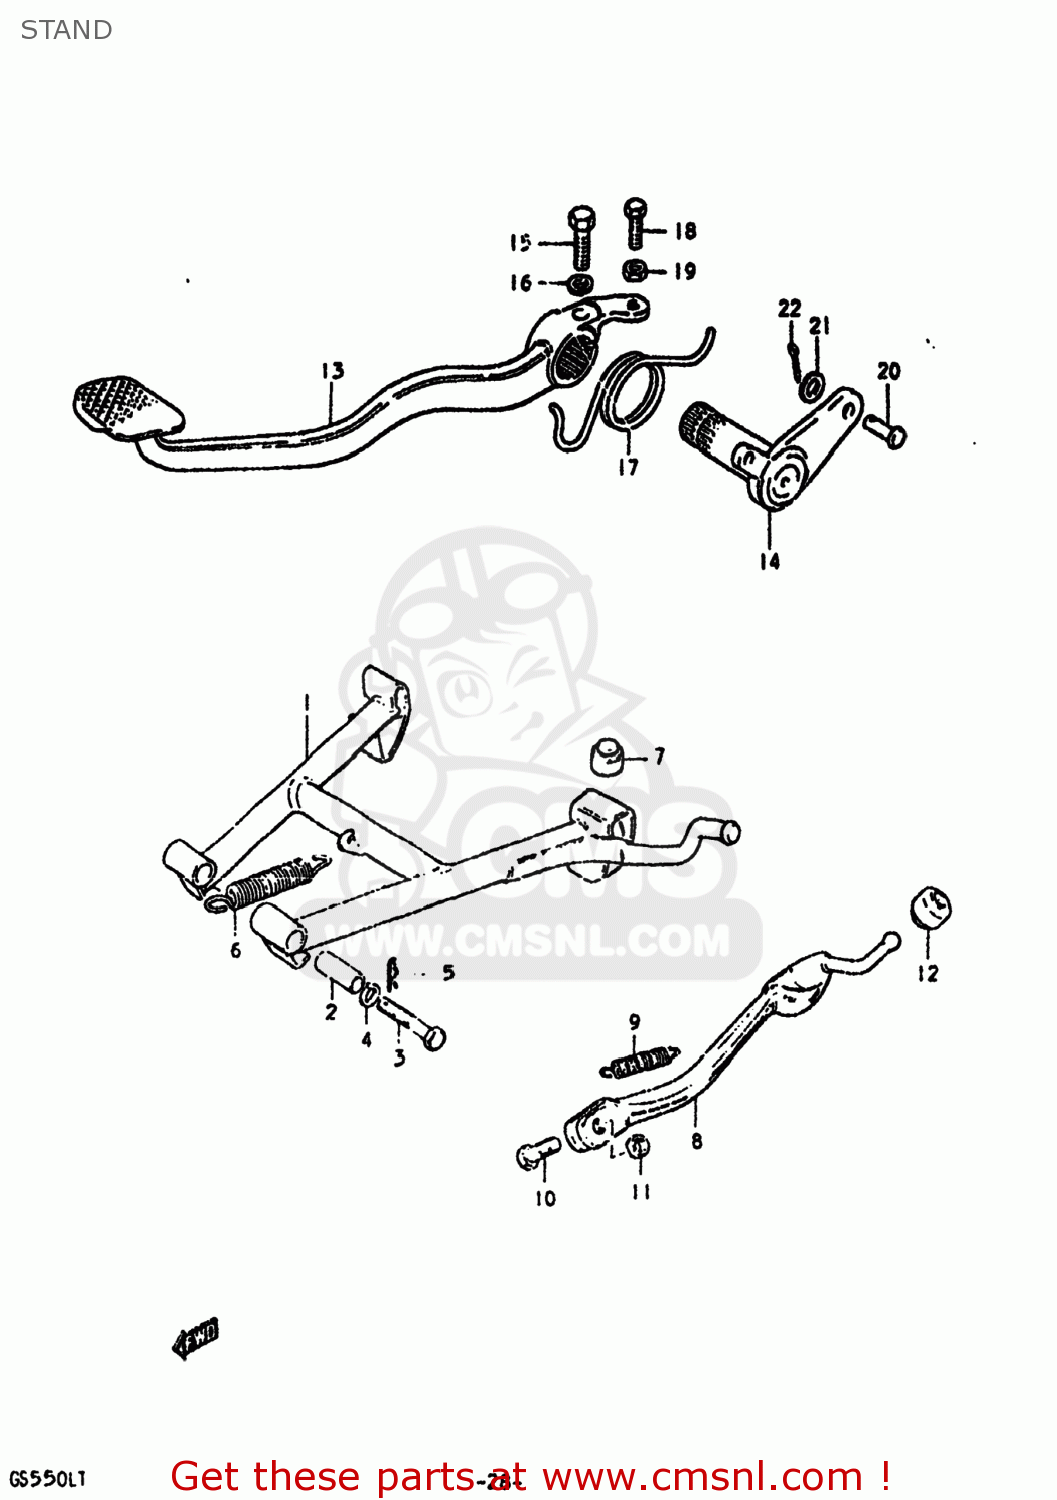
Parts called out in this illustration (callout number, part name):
1	STAND,CENTER
2	SPACER(10X16X38.8)
3	BOLT
4	LOCK WASHER
5	CLIP
6	SPRING
7	CUSHION
8	STAND,SIDE
9	SPRING
10	BOLT(10X30)
11	NUT
12	CUSHION
13	PEDAL,BRAKE
14	ARM,BRAKE PEDAL ROD
15	BOLT
16	LOCK WASHER
17	SPRING
18	BOLT
19	NUT
20	PIN
21	WASHER
22	PIN
